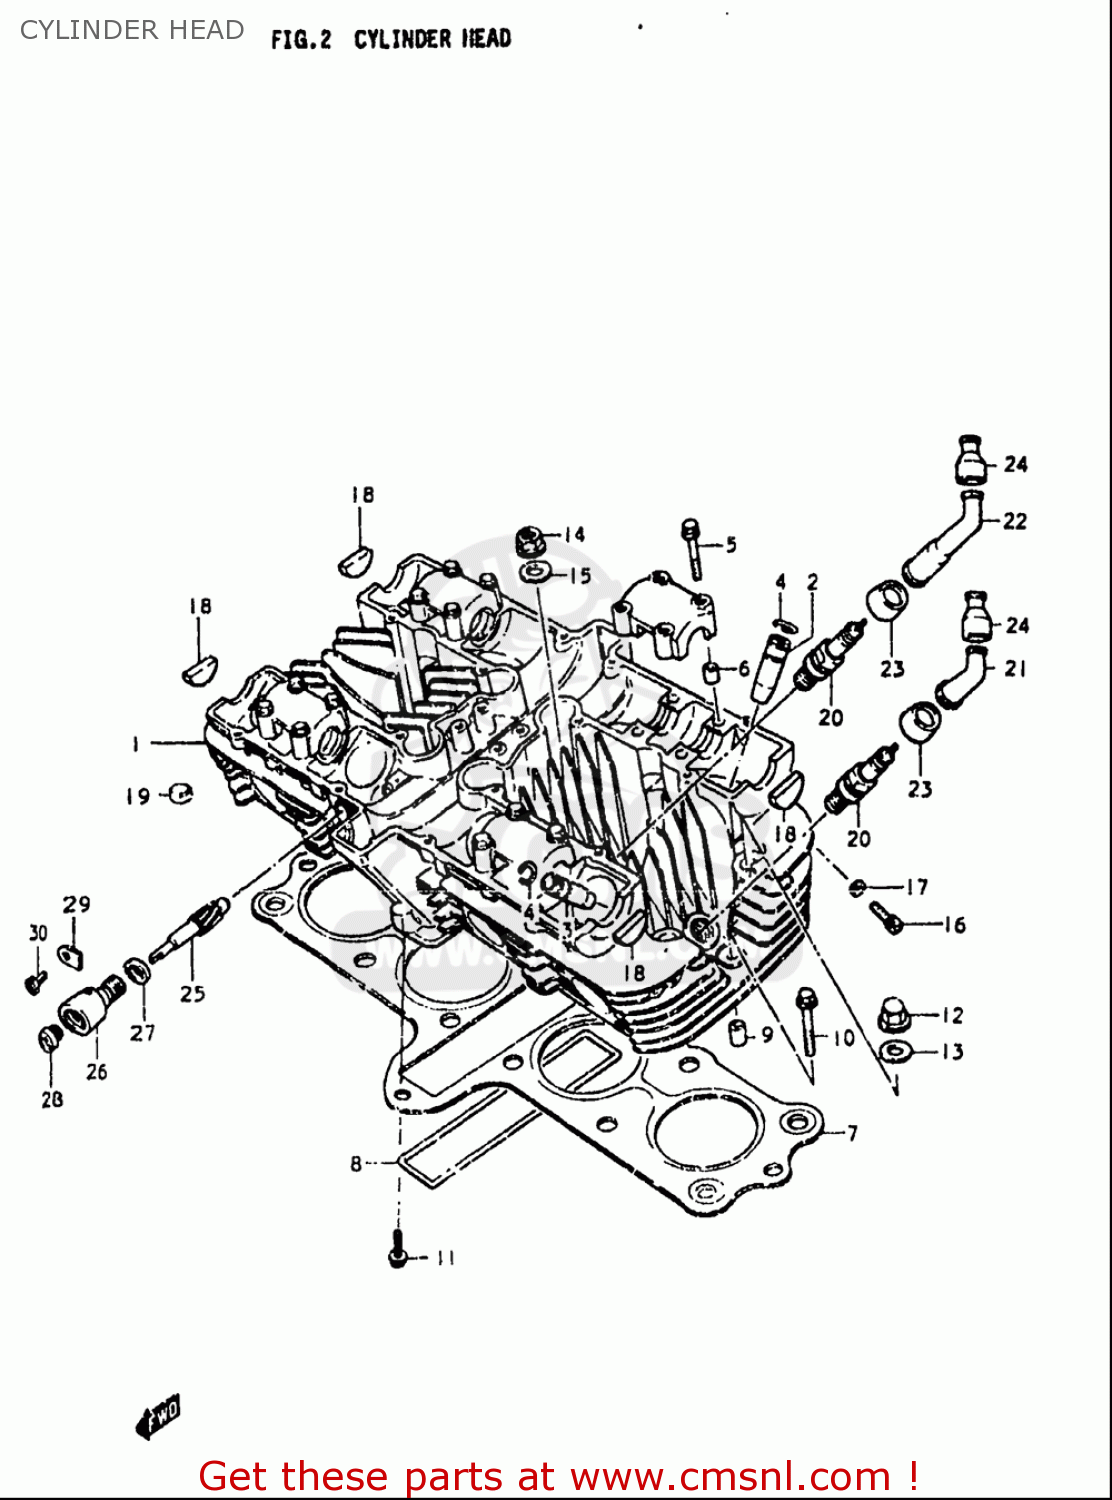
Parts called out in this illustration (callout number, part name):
2	GUIDE,INTAKE VALVE
3	GUIDE,EXHAUST VALVE
4	RING,SNAP
5	BOLT(6X39)
6	PIN(6.2X8X11)
7	GASKET,CYLINDER HEAD (NAS)
8	O RING(D:3,ID:26X157)
9	PIN
10	BOLT
11	BOLT
12	NUT
13	GASKET(10.5X22X2) (NAS)
14	NUT
15	WASHER(10.5X22X2.3)
16	BOLT
17	GASKET(5.3X9.3X1.2) (NAS)
18	PLUG
19	PAD
20	PLUG,SPARK
21	CAP,SPARK PLUG
22	CAP ASSY,SPARK PLUG
23	SEAL,SPARK PLUG
24	SEAL,HIGH TENSION CORD
25	GEAR,TACHOMETER DRIVEN
26	SLEEVE,TACHOMETER DRIVE GEAR
27	SEAL,TACHOMETER DRIVEN
28	SEAL,OIL(5X12X8)
29	PLATE,TACH DRIVE GEAR SLEEVE
30	SCREW(5X12)
